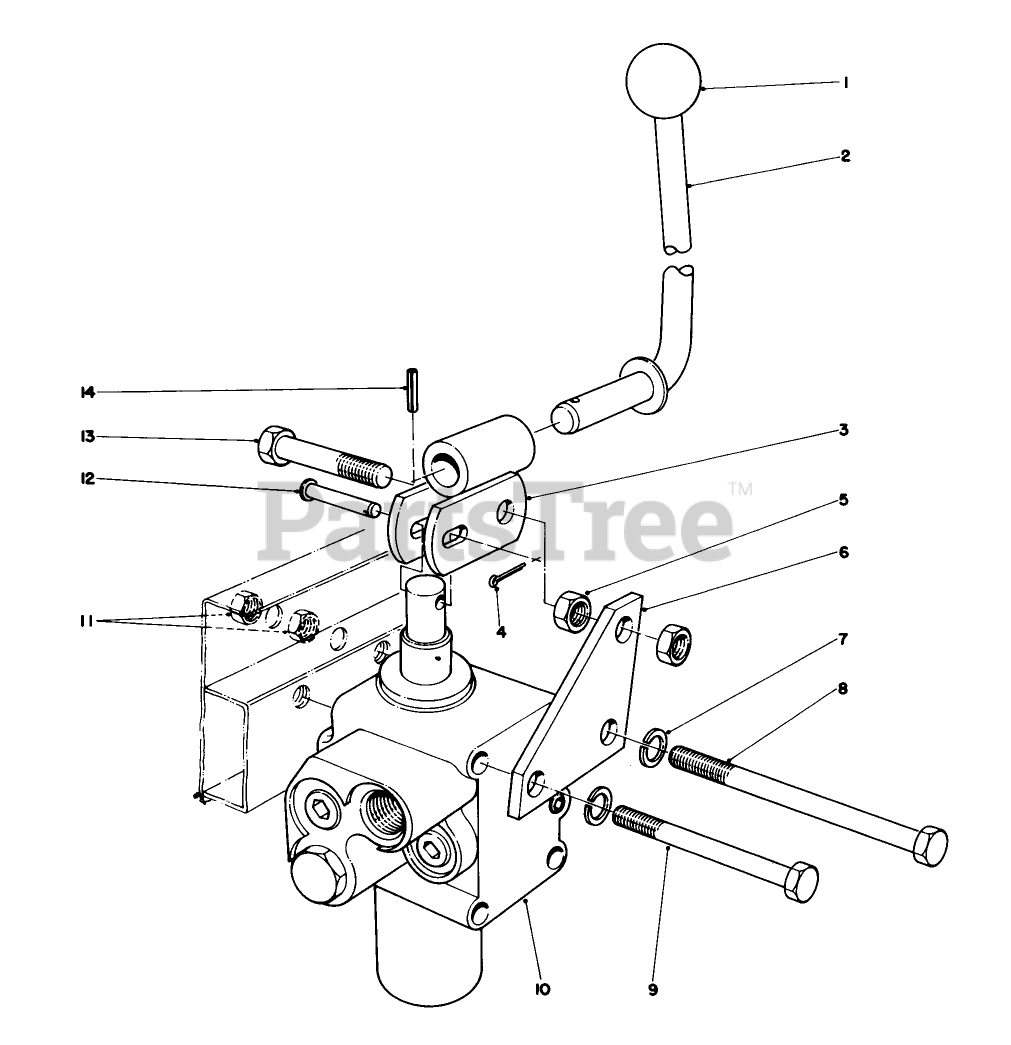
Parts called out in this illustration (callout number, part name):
1	KNOB-CONTROL
2	Valve Lever
3	Valve Lever Link
4	PIN-COTTER
5	NUT-JAM
6	Wheel Bolt
7	WASHER-LOCK
8	SCREW-HH
9	SCREW-HH
10	Valve
11	NUT-HEX
12	PIN-CLEVIS
13	SCREW-HH
14	PIN-ROLL
